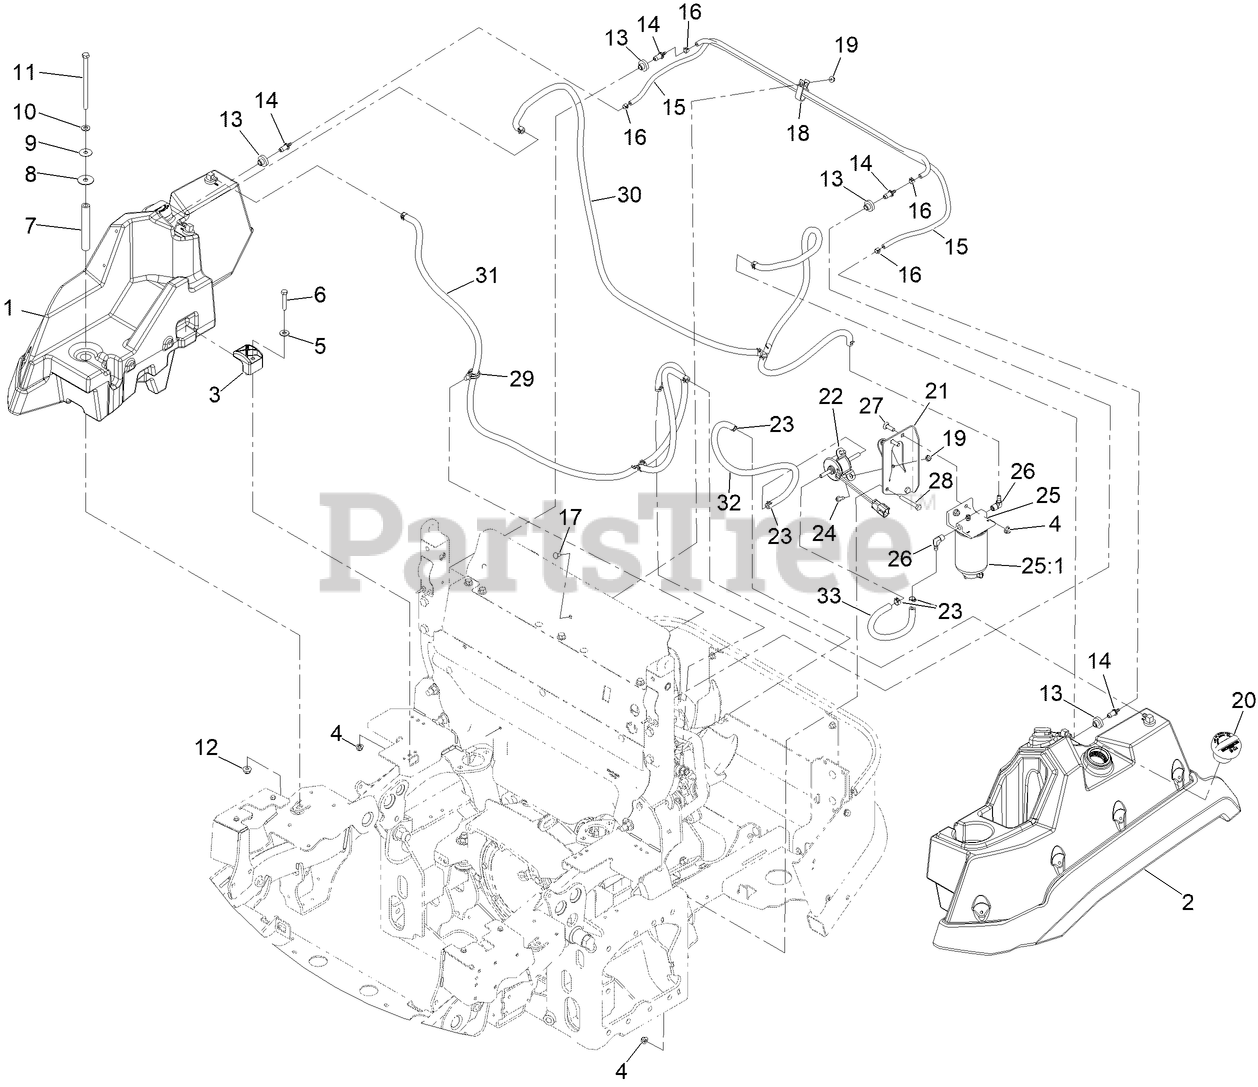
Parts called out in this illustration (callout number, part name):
1	RH FUEL TANK ASM
2	ASM-FUEL TANK, LH
4	NUT-HF, NI
5	WASHER-FLAT
6	SCREW-HH
7	TUBE-SPACER
8	WASHER-RUBBER
9	WASHER-PLAIN
10	WASHER-FLAT
11	SCREW-HH
12	NUT-HF, NI
13	BUSHING
14	FITTING-ORIFICE, STRAIGHT
15	HOSE-VENT, TANK
16	CLAMP-HOSE
17	SCREW-CARR
18	CLAMP-HOSE
19	NUT-HF
20	CAP-FUEL, DIESEL LOW OR ULTRA LOW SULFUR
21	BRACKET-FILTER AND PUMP, FUEL
22	PUMP-FUEL, ELECTRIC
23	CLAMP-HOSE
24	SCREW-HWH
25	SEPARATOR-FILTER
25:1	FILTER-SPIN ON
26	FITTING-HYD, 90
27	SCREW-CARR
28	SCREW-HH
29	CLIP-TIE
30	LINE-FUEL, SUCTION
31	LINE-FUEL, RETURN
32	HOSE-FUEL
33	HOSE-FUEL
